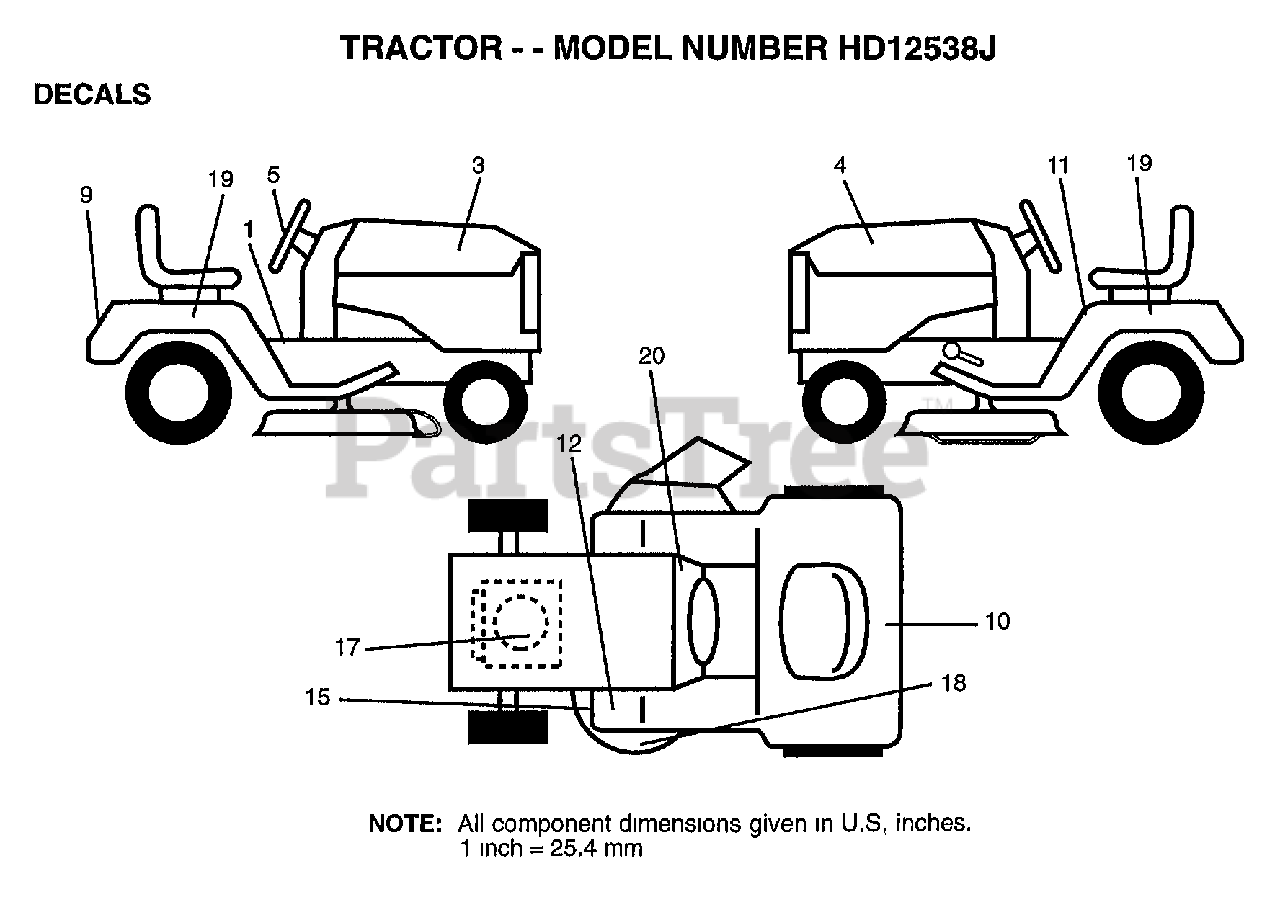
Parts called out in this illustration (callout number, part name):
3	DECAL HOOD RH
4	DECAL HOOD LH
5	DECAL, INS STRG WH
9	DECAL.FENDER.LOGO
10	DECAL.BATRY.3-3908
11	"DECAL FENDER,DANG"
12	DECAL CLUT/BRAKE
15	DECAL
17	DECAL ENGINE
18	DECAL.MOWER.HOME
19	DECAL.FEND.SD.5SP
20	"DECAL,DASH PNL"
